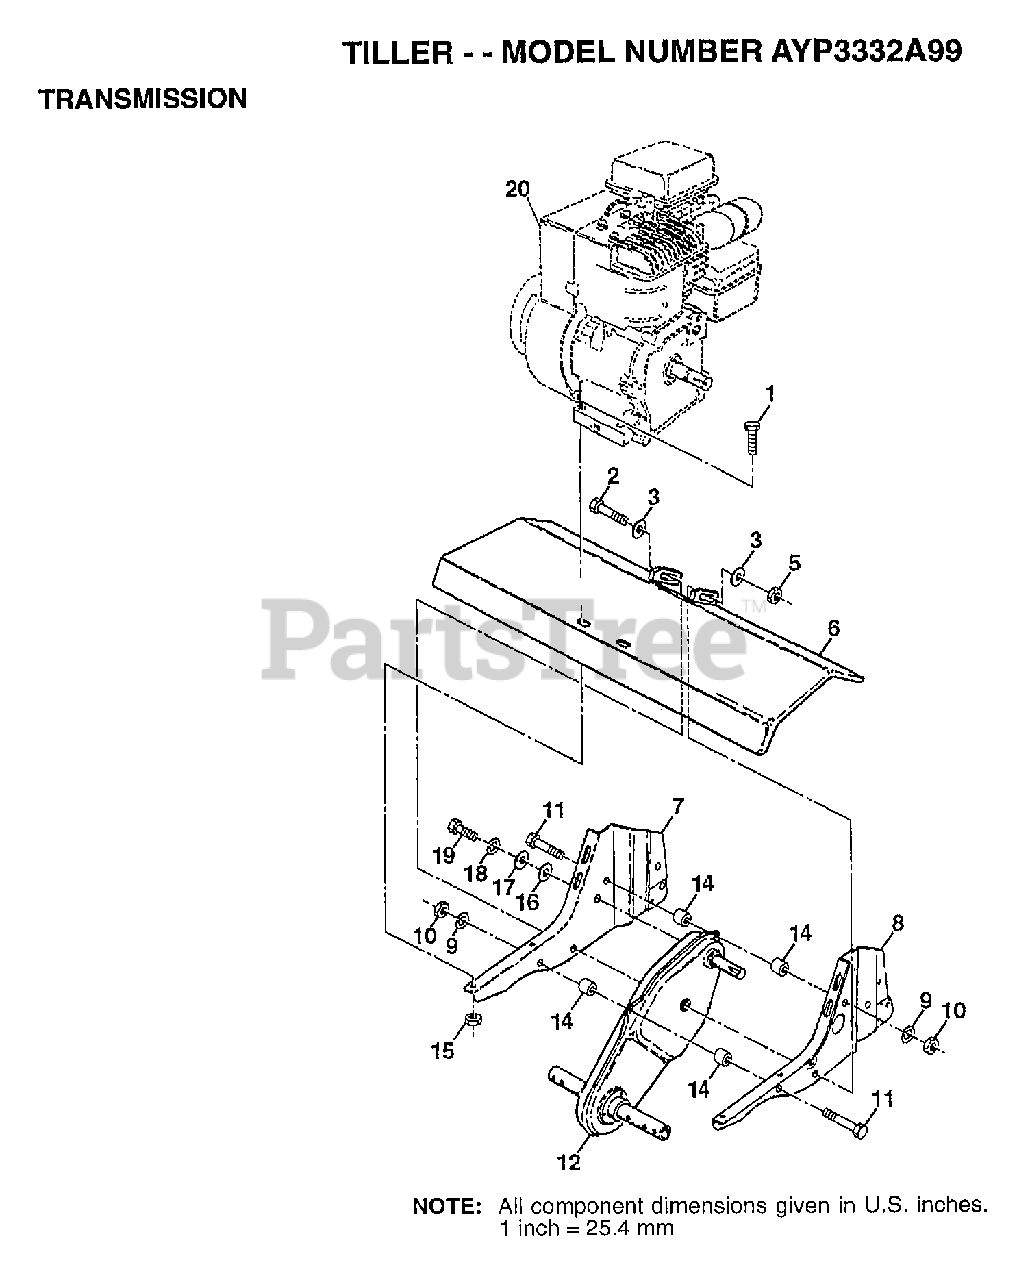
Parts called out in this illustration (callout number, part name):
1	BOLT.HEX.5/16-1.5
2	BOLT HEX 3/8-16
3	WASHER
5	NUT
6	"SHIELD, TINE"
7	BRACKET.ENGINE.RH
8	BRKT.ENGINE.LH
9	LOCKWASHER
10	NUT.HEX.5/16-18
14	SPLIT SPACER RT
16	WASHER
17	WASHER
18	LOCKWASHER
19	BOLT
